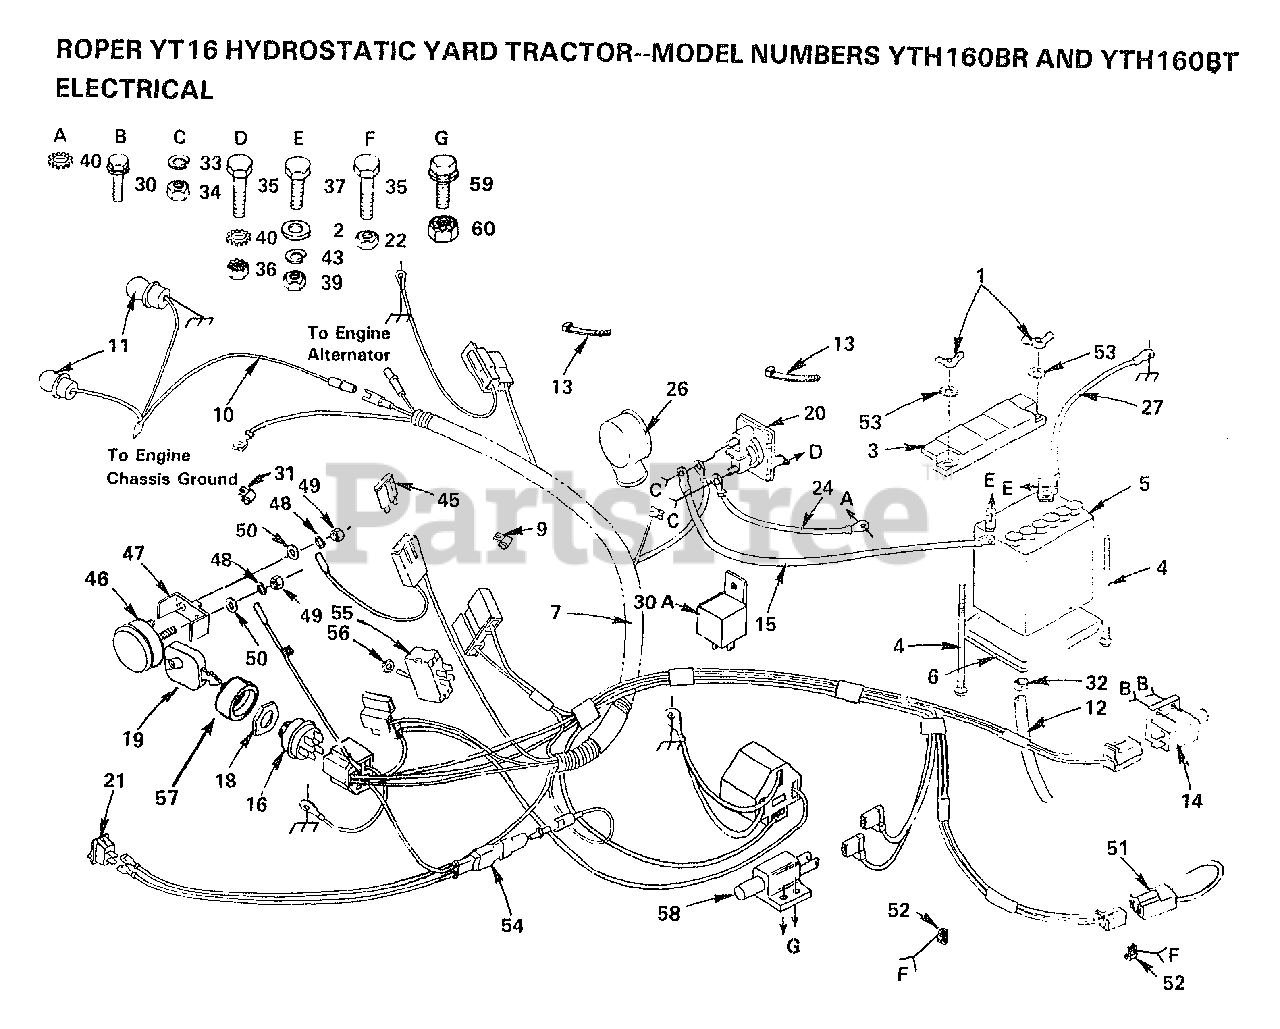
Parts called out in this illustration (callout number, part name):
2	WASHER
4	BOLT
6	"TRAY T, BATTERY"
10	HARNESS T
13	WIRE TIE
14	SWITCH-INTER. GT
15	CABLE-BATTERY T
27	CABLE T
30	SCREW
30A	RELAY ASSY T
31	CLIP T
32	HOSE CLAMP T
34	NUT
35	BOLT
36	NUT
43	LOCKWASHER
45	FUSE HYT
46	AMMETER T
50	WASHER
52	CLIPT
53	LOCKWASHER GT
55	SWITCH.PTO.T
56	HEX NUT T
58	SWITCH T
59	SCREW
60	"NUT,KEPS"
